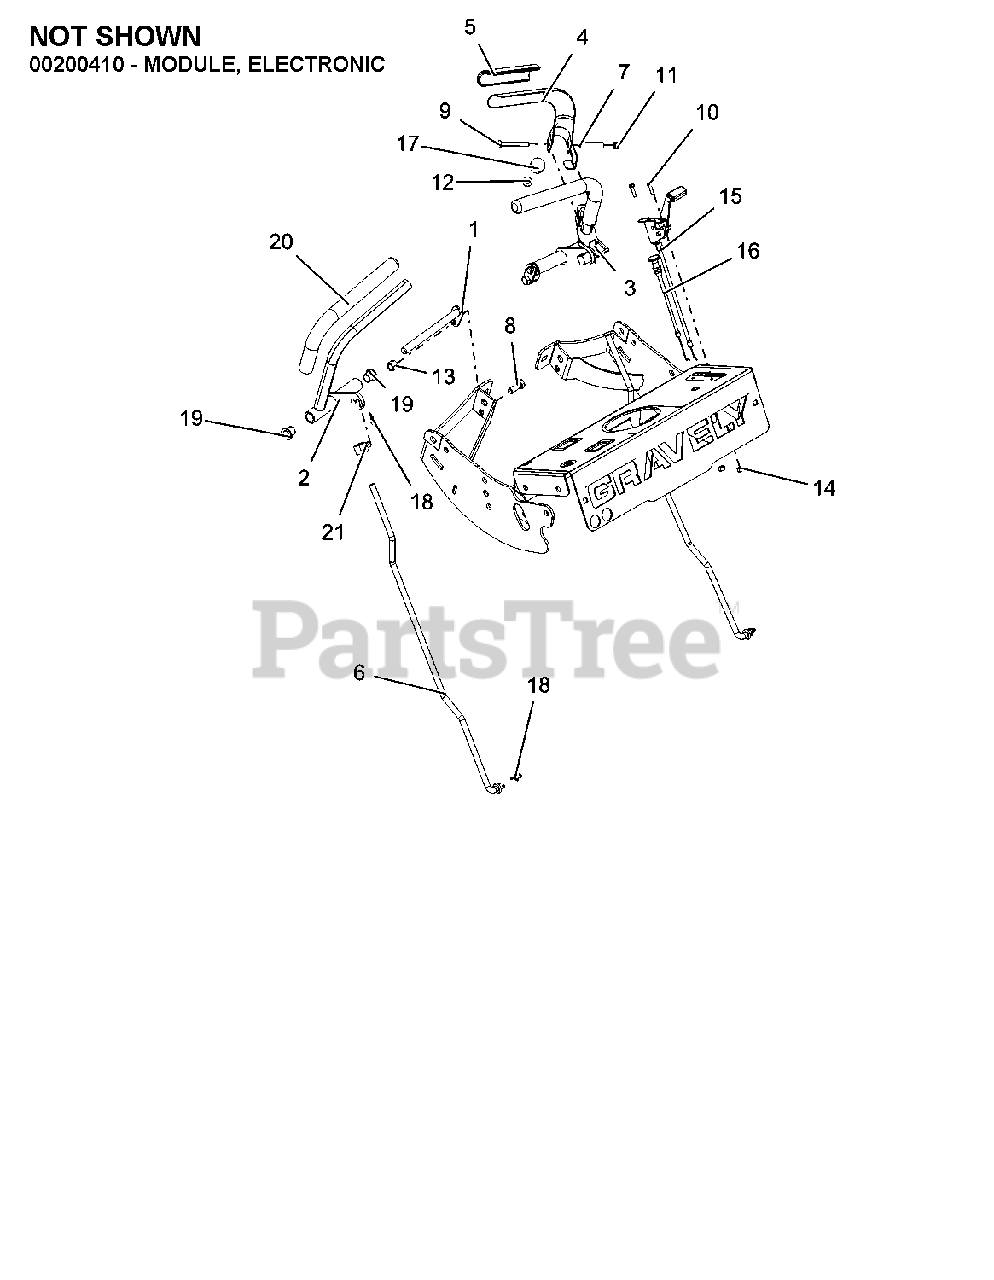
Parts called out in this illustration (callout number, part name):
1	WLDMT, PIN & LOCK
2	WLDT, RH DRIVE LEVER 5 DEG-BLACK
3	WLDT, LH DRIVE LEVER-BLACK
4	WMT, OPC HANDLE-BLACK
5	GRIP, CLUTCH LEVER, LH AND RH
6	ROD, DRIVE TWIN LOOP DBL OFST
7	BSHG, OPERATOR PRESENCE
8	BLT-HEX .38-16X1.00 GR5 YWZC
9	BLT-HEX .25-20X2.00 GR5 YWZC
10	@SCR-MCH 10-24X.75 HWH YWZC
11	NUT-LK-CTR .25-20 YWZC
12	@NUT-SPNLK-FLG .312-18 YWZC
13	NUT-LK-NYL .38-16 YWZC
14	NUT-LK-NYL #10-24 YWZC
15	CABLE, THROTTLE 43"
16	CABLE, CHOKE 43"
17	BUMPER, RUBBER
18	RING, RUE .375 x .054 x 1.254
19	BRG, FLG .500 X .625 X .500 BRNZ
20	GRIP, CONTROL
21	SWIVEL, 3/8-24
